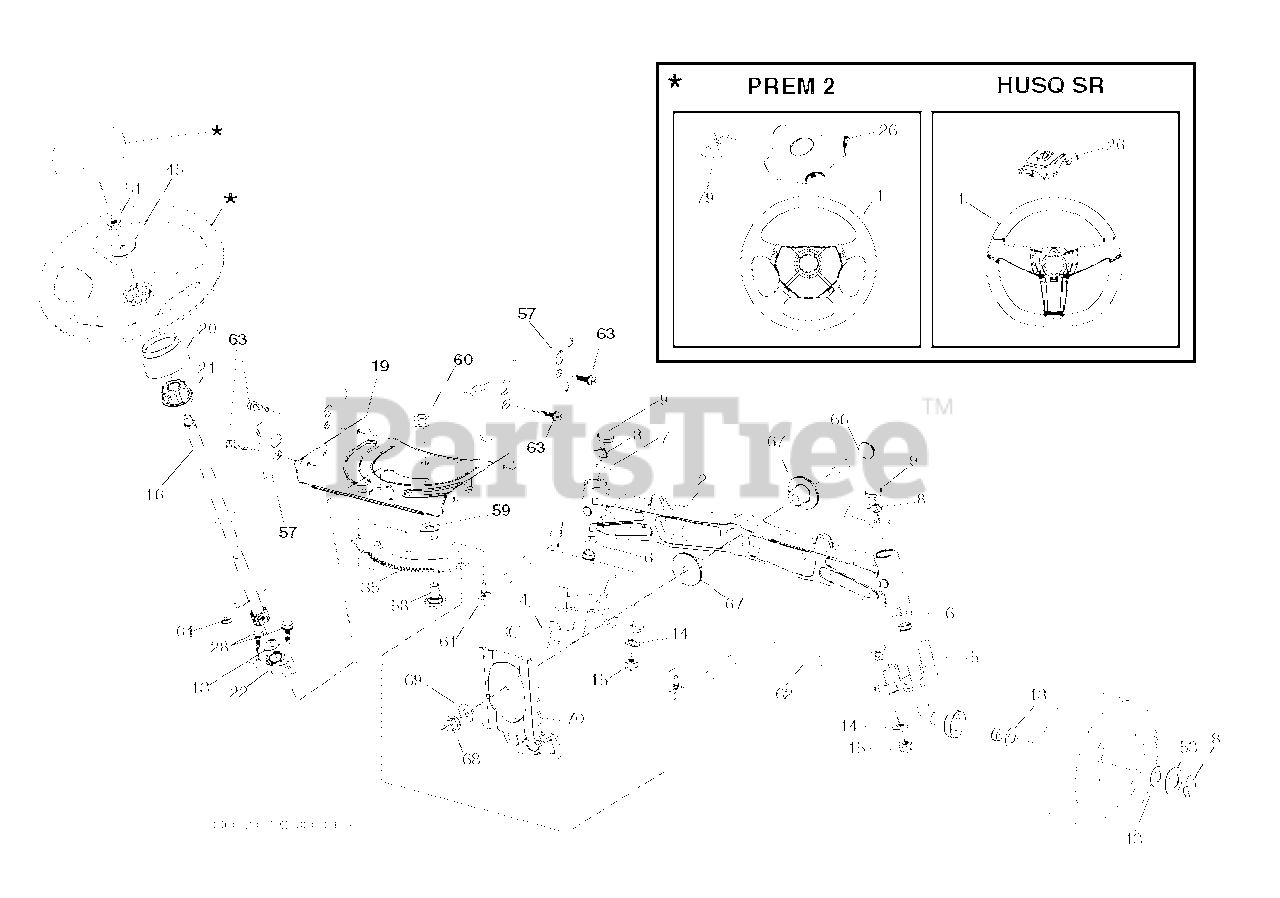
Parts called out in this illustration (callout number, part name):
1	WHEEL.STEERING.PREM.2.BLK
2	AXLE.CAST.IRON
4	SPINDLE.WELDED.LH.15"TEX
5	SPINDLE.WELDED.RH.15"T
8	RING CLIP
9	CAP.SPINDLE
14	WASHER, LOCK 3/8
15	NUT CROWNLOCK 3/8-24
16	SHAFT.STEER.STEALTH.DD
19	PLATE.STEER.DDL.NLT/NG
20	BOOT.STEERING.
21	ADAPTER, WHEEL STNG..
22	BUSHING.ASM.STEERING.A
26	INSERT.CAP.STRG.WH.BLACK
28	SCREW, 3/8-16X3/4
35	GEAR.SECTOR.PLATE.DDL.
45	WASHER.11/32
51	NUT.HEX.1/2-20
53	WASHER.HARDENED
57	BRACKET.UPSTOP.TEX
58	BOLT.SHOULDER.SECTOR.P
59	WASHER.THURST.SECTOR.S
60	NUT FLANGE LOCK 5/8-11
61	DRAGLINK.LH.BALLSTUD.D
62	DRAGLINK.RH.BALLSTUD.D
63	SCREW
64	RETAINER.CLIP.SPRING.S
66	BOLT HEX FGHD 7/16-14 X 3 SERR
67	BUSHING.PM.FRONT AXLE
68	NUT.LOCK.FLANGE.7/16
69	WASHER.1.5X.505X.118
70	BRKT.DECK.SUSPENSION.F
